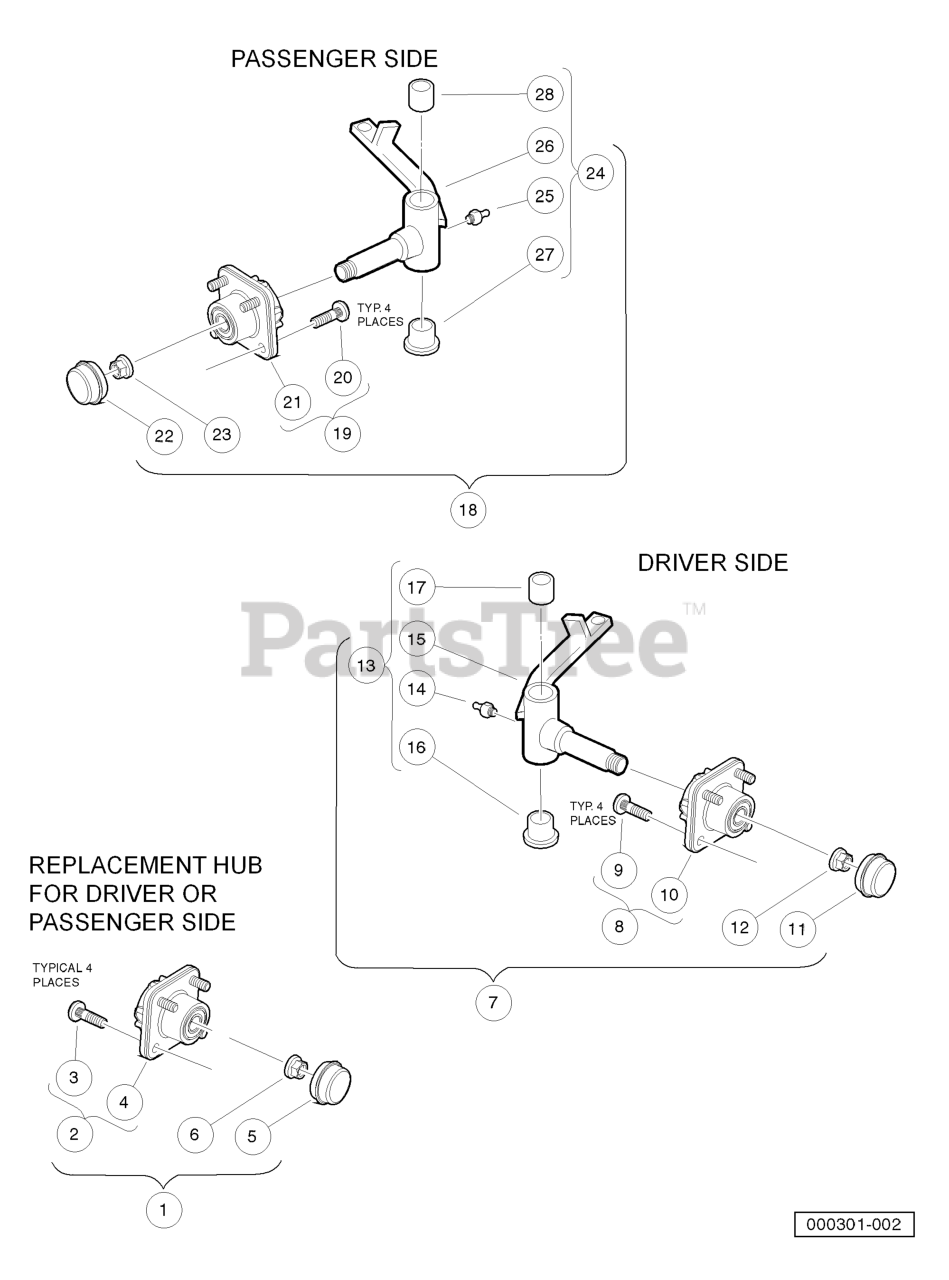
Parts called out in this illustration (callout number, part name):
1	REPLACEMENT KIT, FRONT HUB
2	Front Hub Assembly, Ball Bearing
3	LUG STUD, 1/2-20 UNF, 4037 STL
4	Hub, Front
5	CAP, FRONT HUB
6	HEX NUT, LOCKING FLANGE, M14X2
7	Asm, Hub And Spindle, Left-Hand Ext
8	Front Hub Assembly, Ball Bearing
9	LUG STUD, 1/2-20 UNF, 4037 STL
10	Hub, Front
11	CAP, FRONT HUB
12	HEX NUT, LOCKING FLANGE, M14X2
13	ASM, SPINDLE, LH, EXT
14	FITTING, 1/4-28 THRD FRM GREAS
15	Subasm, Spindle, LH, Ext
16	BUSHING, FLANGED BROZE
17	BUSHING BRONZE SPINDLE
18	Asm, Hub And Spindle, Right-Hand Ext
19	Front Hub Assembly, Ball Bearing
20	LUG STUD, 1/2-20 UNF, 4037 STL
21	Hub, Front
22	CAP, FRONT HUB
23	HEX NUT, LOCKING FLANGE, M14X2
24	ASM, SPINDLE, RH, EXT
25	FITTING, 1/4-28 THRD FRM GREAS
26	Subasm, Spindle, RH, Ext
27	BUSHING, FLANGED BROZE
28	BUSHING BRONZE SPINDLE
